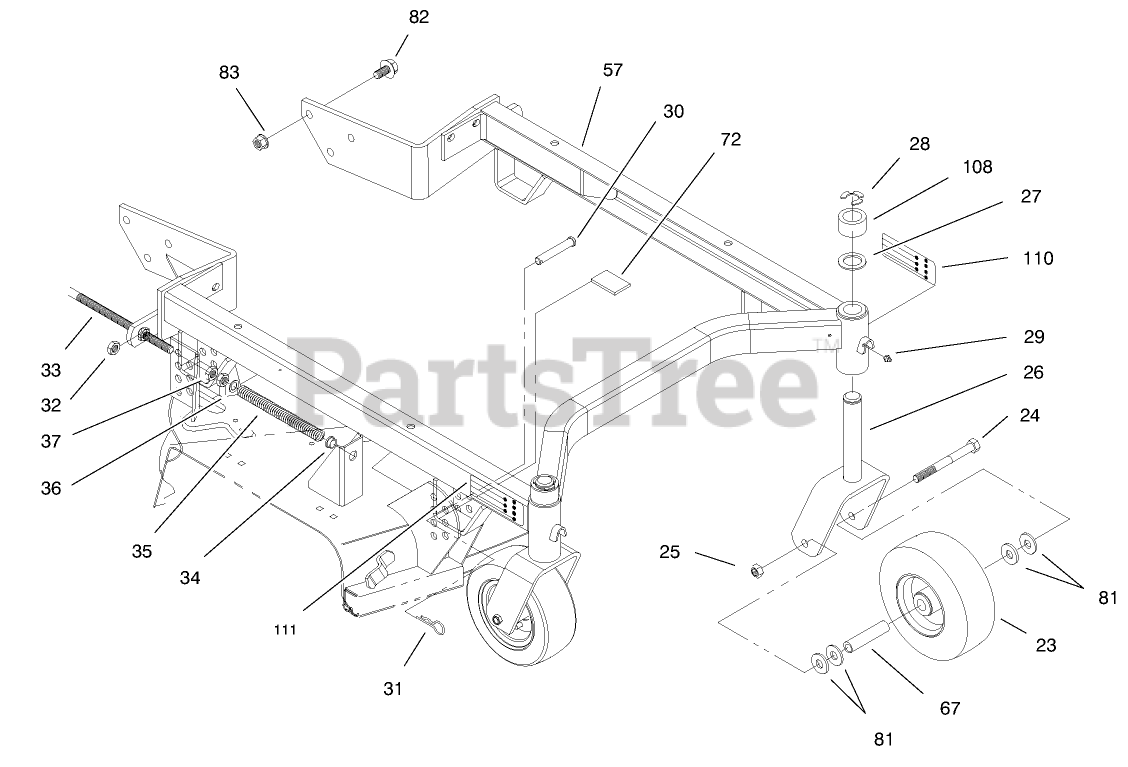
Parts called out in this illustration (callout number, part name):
23	CASTOR WHEEL ASM
24	SCREW-HH
25	NUT-HEX
26	Castor Fork
27	WASHER-THRUST
28	RING-RETAINING
29	FITTING-GREASE
30	PIN-CLEVIS
31	PIN-HAIR
32	NUT-LOCK, NI
33	SHAFT-ADJUSTING
34	BUSHING-FLANGE
35	SPRING
36	WASHER
37	NUT-JAM
57	FRAME ASM
67	SPANNER-TIRE
72	CUSHION-RUBBER
81	WASHER-FLAT
82	SCREW-HHF
83	NUT-HF
108	SPACER-CASTOR
110	DECAL-HOC, LH
111	DECAL-HOC, RH
